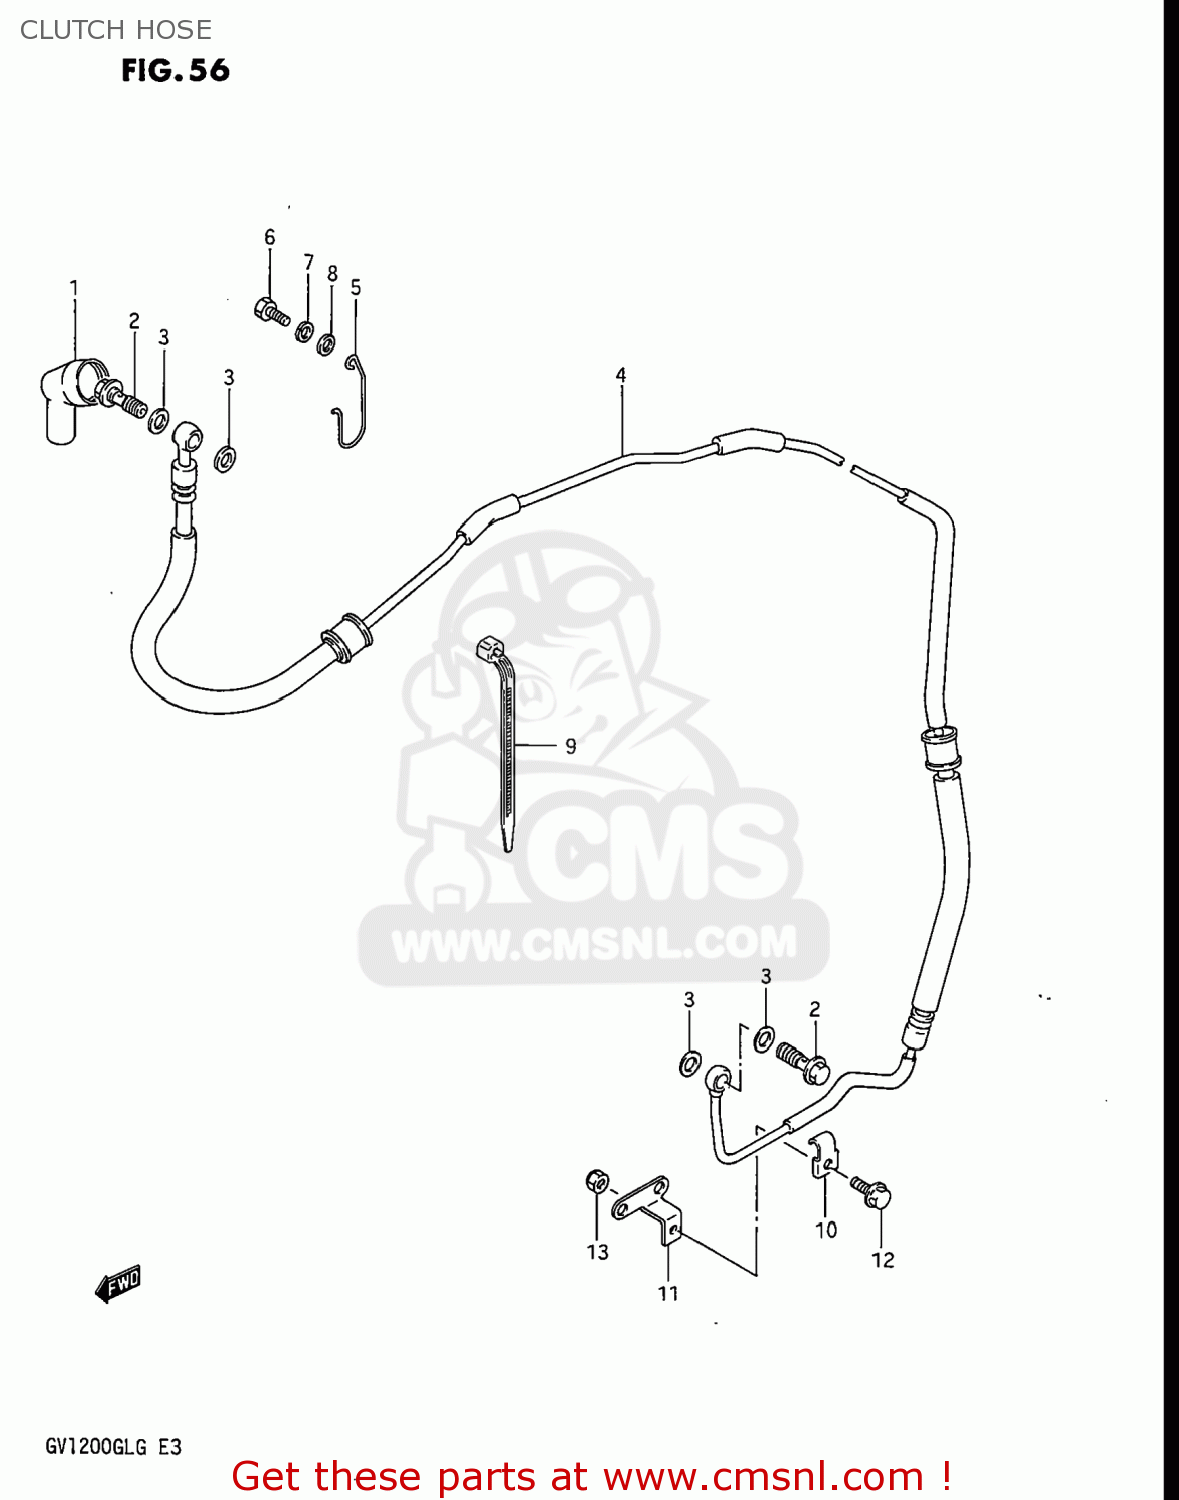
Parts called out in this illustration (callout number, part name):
1	BOOT,MASTER CYLINDER
2	BOLT UNION
3	WASHER(10X15X1.5)
4	HOSE,CLUTCH
5	GUIDE,CLUTCH HOSE
6	BOLT
7	WASHER,LOCK
8	WASHER
9	CLAMP(L:165)
10	GUIDE,CLUTCH HOSE
11	CLAMP,CLUTCH HOSE
12	BOLT 6X12
13	NUT
